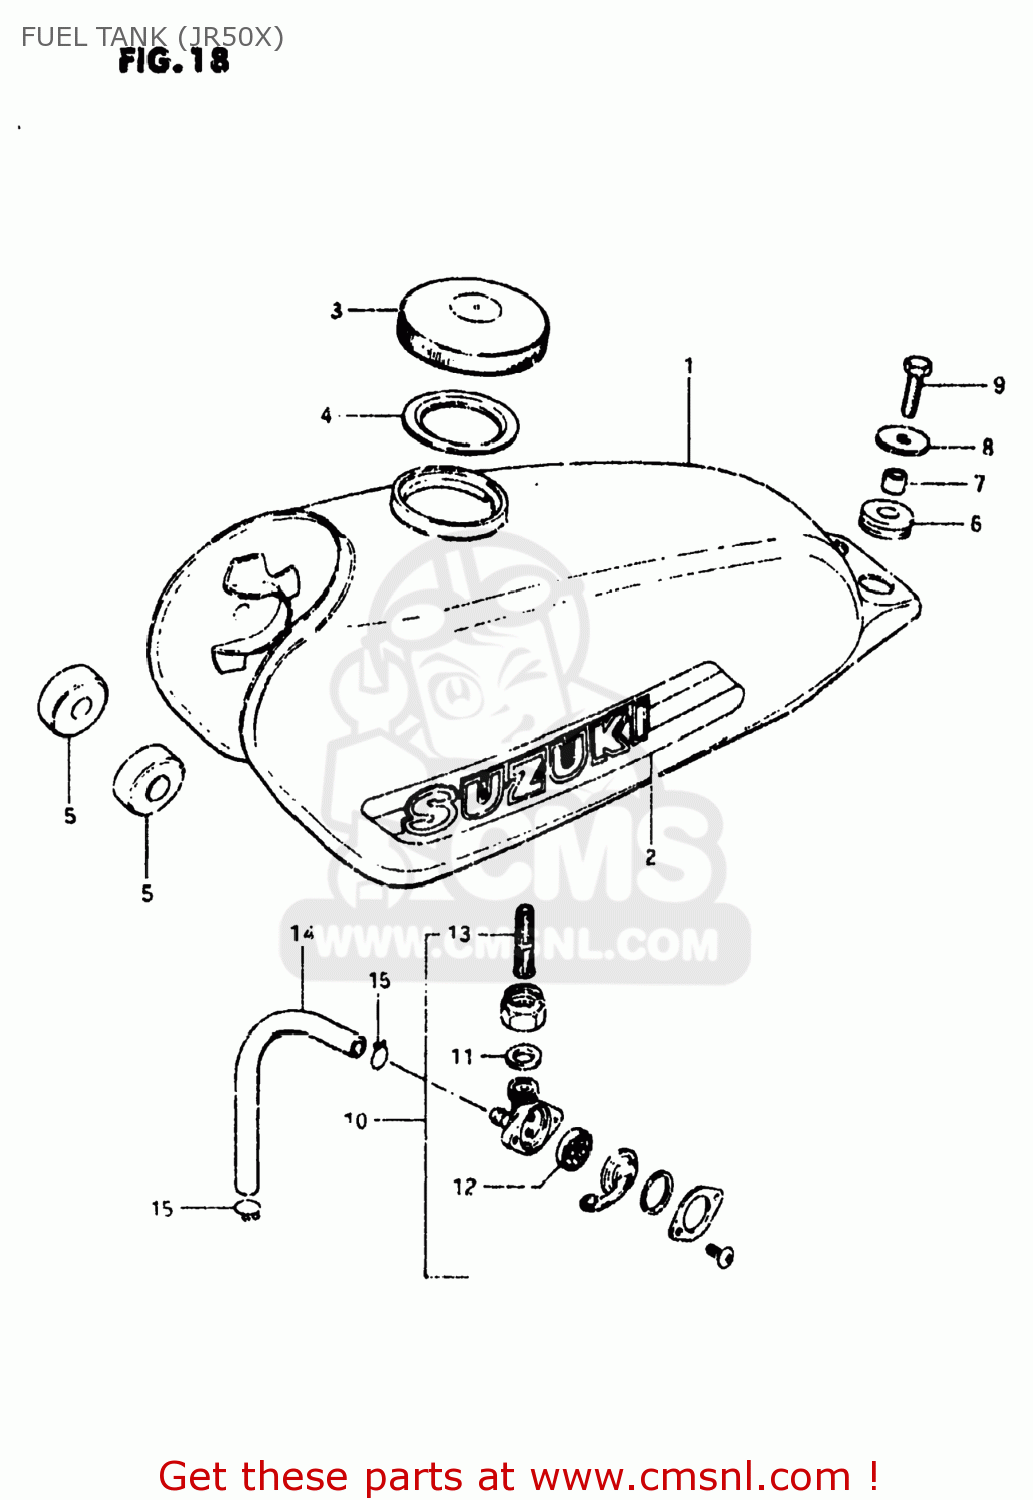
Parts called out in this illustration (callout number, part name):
1	TANK ASSEMBLY,FUEL
2	TAPE SET,FUEL TANK
3	CAP SET,FUEL TANK
4	GASKET,CAP (NAS)
5	CUSHION
6	CUSHION
7	SPACER(6.1X9X7.5)
8	WASHER (6.5X24X1.6)
9	BOLT, UPPER
10	COCK ASSEMBLY,FUEL
11	GASKET,FUEL COCK (NAS)
12	PACKING,VALVE (NAS)
13	FILTER,FUEL
14	HOSE
15	CLIP
